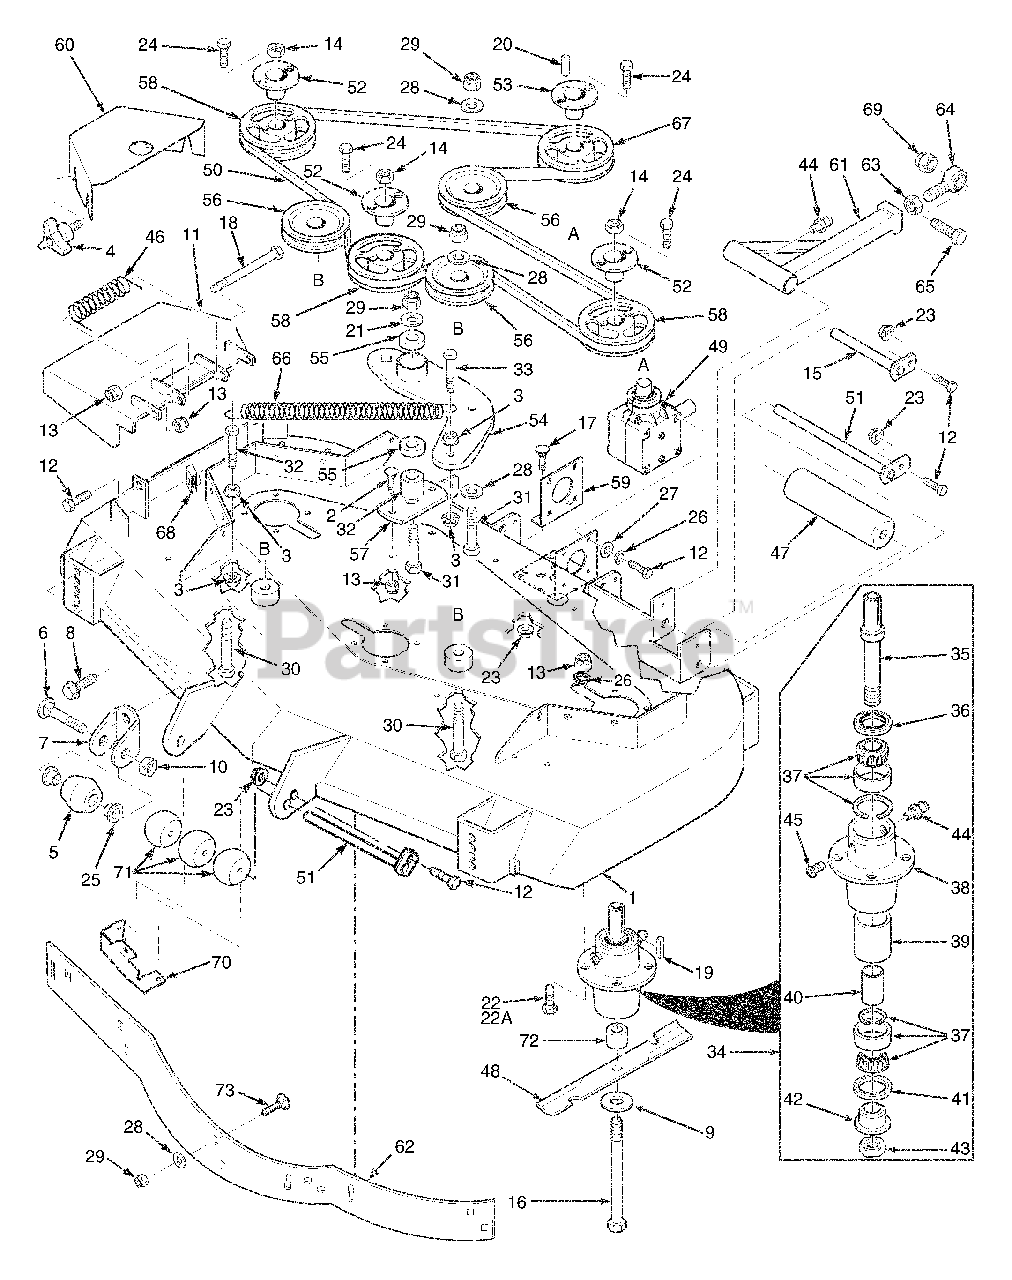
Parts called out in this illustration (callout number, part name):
1	Cutter Deck, 72" Advantage
2	Bolt, Carriage 5/16-18 x 1"
3	Nut, Hex Serrated Flange 3/8-16
4	Wing Nut, 3/8-16
5	Anti-Scalp Wheel
6	Bolt, Carriage 3/8-16 x 4"
7	Anti-Scalp Wheel Bracket
8	Bolt, Hex Serrated Flange 3/8-16 x 1"
9	Flatwasher, 5/8" Hardened
10	Locknut, 3/8-16 Center Lock
11	Discharge Chute, 61" & 72" Adv.
12	Bolt, Hex Head 5/16-18 x 1.75" (Front)
13	Nut, Hex Elastic Stop 5/16-18
14	Nut, 5/8-11 UNC
15	Push Arm Shaft
16	Bolt, Hex Head 5/8-11 x 9.50"
17	Bolt, Carriage 5/16-18 x .75"
18	Bolt, Hex Head 5/16-18 x 4.75"
19	Key, 1/4 x 1/4 x 2"
20	Key, 1/4 x 1/4 x 1.25"
21	Flatwasher,3/8-.39 x .938 x .105 HD
22	Bolt, Hex Head 5/16-18 x 1.50"
22A	Bolt, Hex Head 5/16-18 x 1.75"
23	Nut, Hex Serrated Flange 5/16-18
24	Bolt, Hex Head 1/2-20 x .75"
25	Bushing, .376 I.D. Oilite
26	Lockwasher, 5/16"
27	Flatwasher, 5/16" (.375 x .875 x .083)
28	Flatwasher, 3/8" (.391 x .938 x .105)
29	Nut, Hex Elastic Stop 3/8-16
30	Bolt, Hex Head 3/8-16 x 3.25"
31	Bolt, Hex Head 3/8-16 x 2.50"
32	Pivot, Idler - Short
33	Bolt, Hex Head 3/8-16 x 1.50" Grade 8
34	Spindle Assembly
35	Spindle Shaft
36	Seal, Top
37	Bearing Assembly
38	Spindle Housing
39	Spacer, Outside
40	Spacer, Inside
41	Seal, Bottom
42	Spindle Bushing, Bottom
43	Nut, Special 1 - 1/16-18
44	Grease Fitting
45	Relief Fitting, Tapered Spindle
46	Spring, Discharge Chute
47	Guide, Roller
48	Cutter Blade, 24.5" 72"
49	Gearbox Assembly, Deck Drive
50	Belt, Cutter Deck Drive, 72"
51	Roller Shaft
52	Tapered Hub, 1-1/8" Bore
53	Tapered Hub, 1" Bore
54	Idler Arm, Cutter Deck
55	Bearings, Ball
56	Pulley, Idler
57	Base, Idler Pivot
58	Pulley, 6.95 O.D. - 72"
59	Mounting Plate, Gearbox
60	Belt Cover, LH - 72"
61	Pusharm
62	Baffle, Custom Cut 72A
63	Nut, Hex Head 5/8-18 UNF
64	Rod End, 5/8" Male RH Thread
65	Bolt, Hex Head 5/8-11 x 4-1/2"
66	Spring, Cutter Deck
67	Pulley, 6.35 O.D. - 72"
68	U-Nut, 3/8-16
69	Nut, Hex Elastic Stop 5/8-11
70	Discharge Baffle 72"
71	Wheel, Anti-Scalp
72	Spacer, Spindle Bottom
73	Bolt, Carriage 3/8-16 x 1"
04001.11	Bolt, Hex Head 5/16-18 x 150" (Rear)
